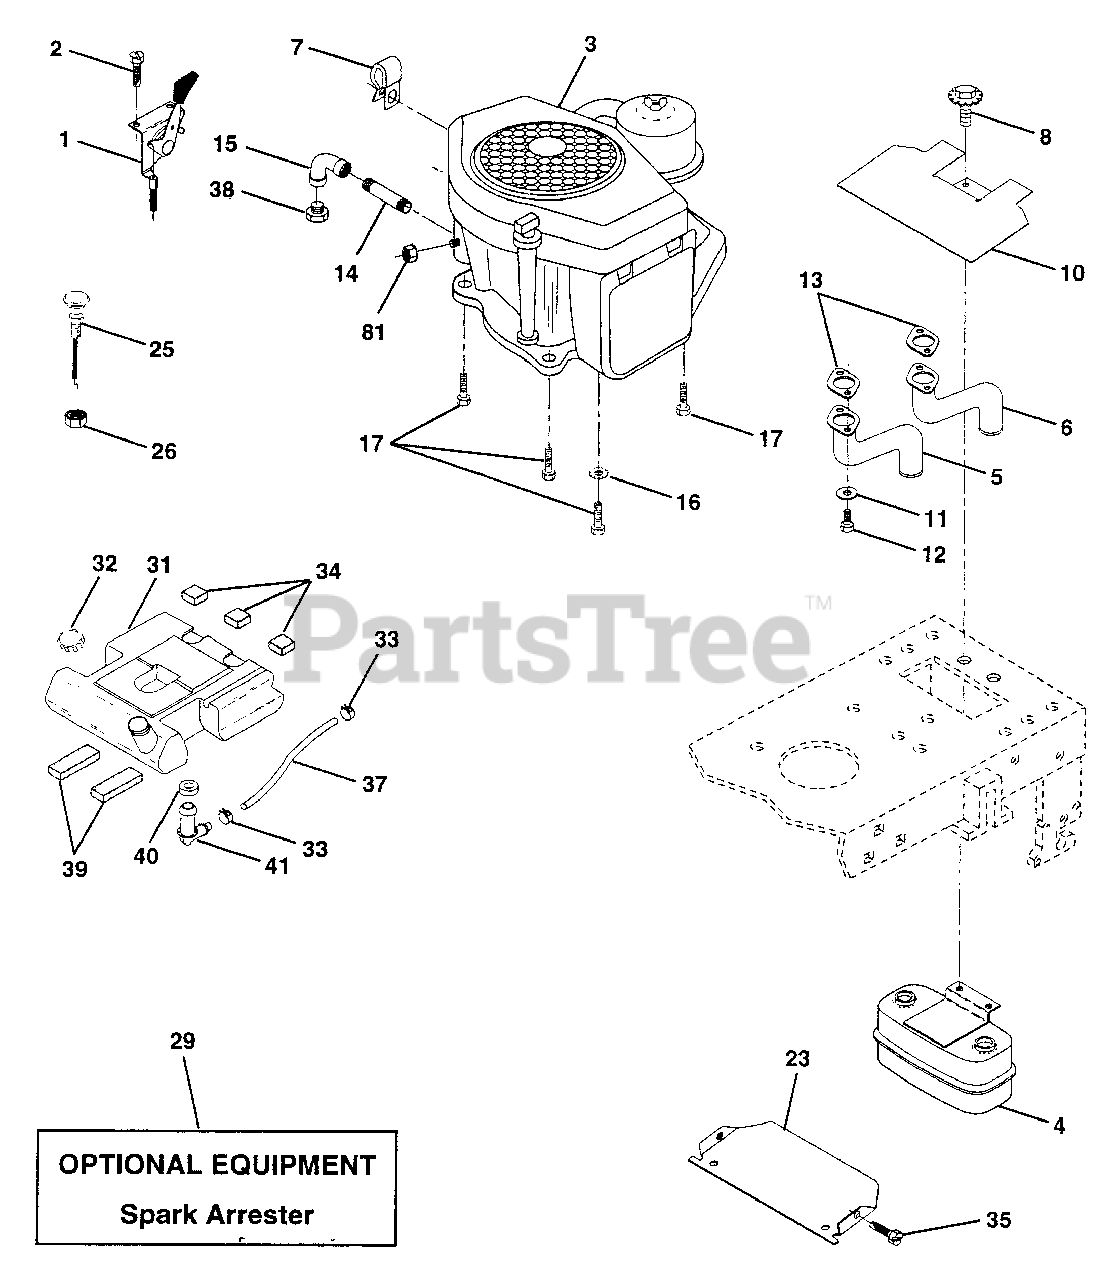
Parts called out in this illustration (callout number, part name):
1	Control Throt Flg 180 LH
2	Screw Hex Thd Cut 1/4-20x5/8 T
4	Muffler Asm Twin Lo-Tone
5	Pipe Exhaust CV18/20 LH
6	Pipe Exhaust CV18/20 RH
7	Clip, Fuel Line
8	Bolt 5/16-18unc x 3/4 W/Sems
10	Shield Heat Muffler CV18/20
13	Muffler Gasket
14	Nipple Pipe 3/8 Npt X 4-1/2"
15	Elbow Std 90 Degree 3/8-18 Npt
16	Washer Lock Ext Tooth 3/8
17	Screw Thdrol 3/8-16 x 1-1/2
23	Shield Browning
25	Choke Control 37"
26	Nut, Keps 3/8-24 Unf
29	Kit Spark Arrestor (Flat Scm)
31	Tank Fuel 3 50 Rear
32	Cap Asm Fuel Top N/Lany Vented
33	Clamp Hose Blk
34	Pad, Spacer
35	Screw Thdrol 5/16-18 x 3/4
37	Line Fuel 7.5
38	Plug Oil Drain
39	Pad, Idler
40	Bushing
41	Stem Tank Fuel
81	Nut Flange 1/4-20 Starter Nut
